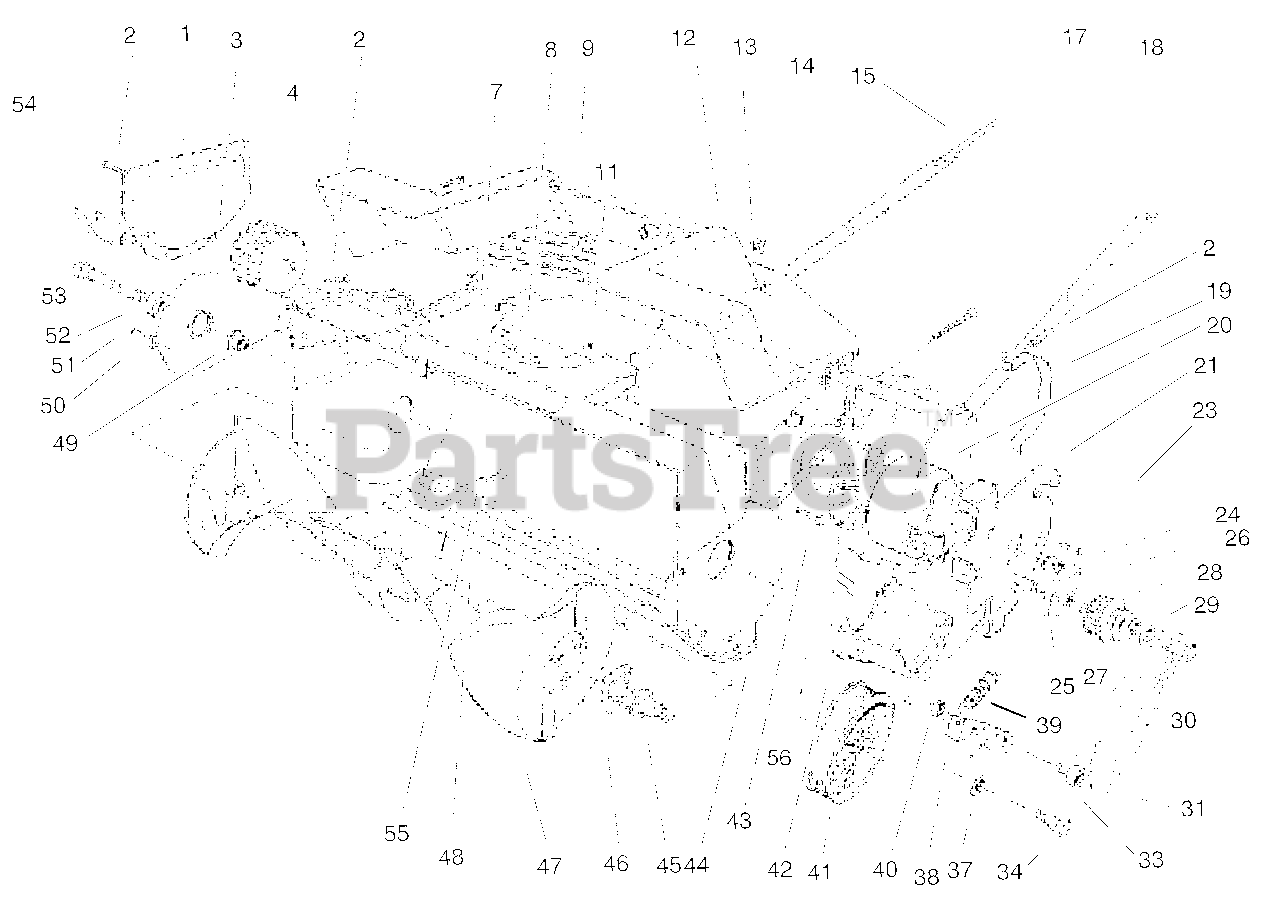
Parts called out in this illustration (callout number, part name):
1	Plate - Side
2	SCREW-PPH
3	PUSHNUT-CAP, WASHER
7	Shaft-Axle
8	Relief-Strain
9	Decal - Danger
11	Connector
12	Shroud - Housing
14	Tube - Lower Handle
15	Wire Harness
17	Filter-Foam
18	Screw-Pan Head
19	Strap-Motor
21	Motor Plate ASM
23	Screw-Hex Washer Hd.
24	Pulley-Driver
25	Belt-Timing
27	Bearing - Needle
28	Pulley Asm - Idler (Incl. Ref. #27)
29	WASHER-THRUST
30	Bolt-Idler
31	Belt-Drive
33	Bearing Asm (Incl. Ref. #40)
34	SCREW-SHOULDER
38	Bracket-Idler
40	NUT-LOCK, NI
41	Pulley-Driven
42	Clamp-Motor Bracket
44	Housing-Rotor
45	Shaft-Driver, Rotor
46	Coupler-Rotor
50	Bracket - Wheel (Incl. Ref. #52)
51	RIVET-POP
52	BEARING-BALL
53	Shaft-Rotor
54	Skid-Housing
55	Screw - Pan Hd.
56	Filter-RFI
